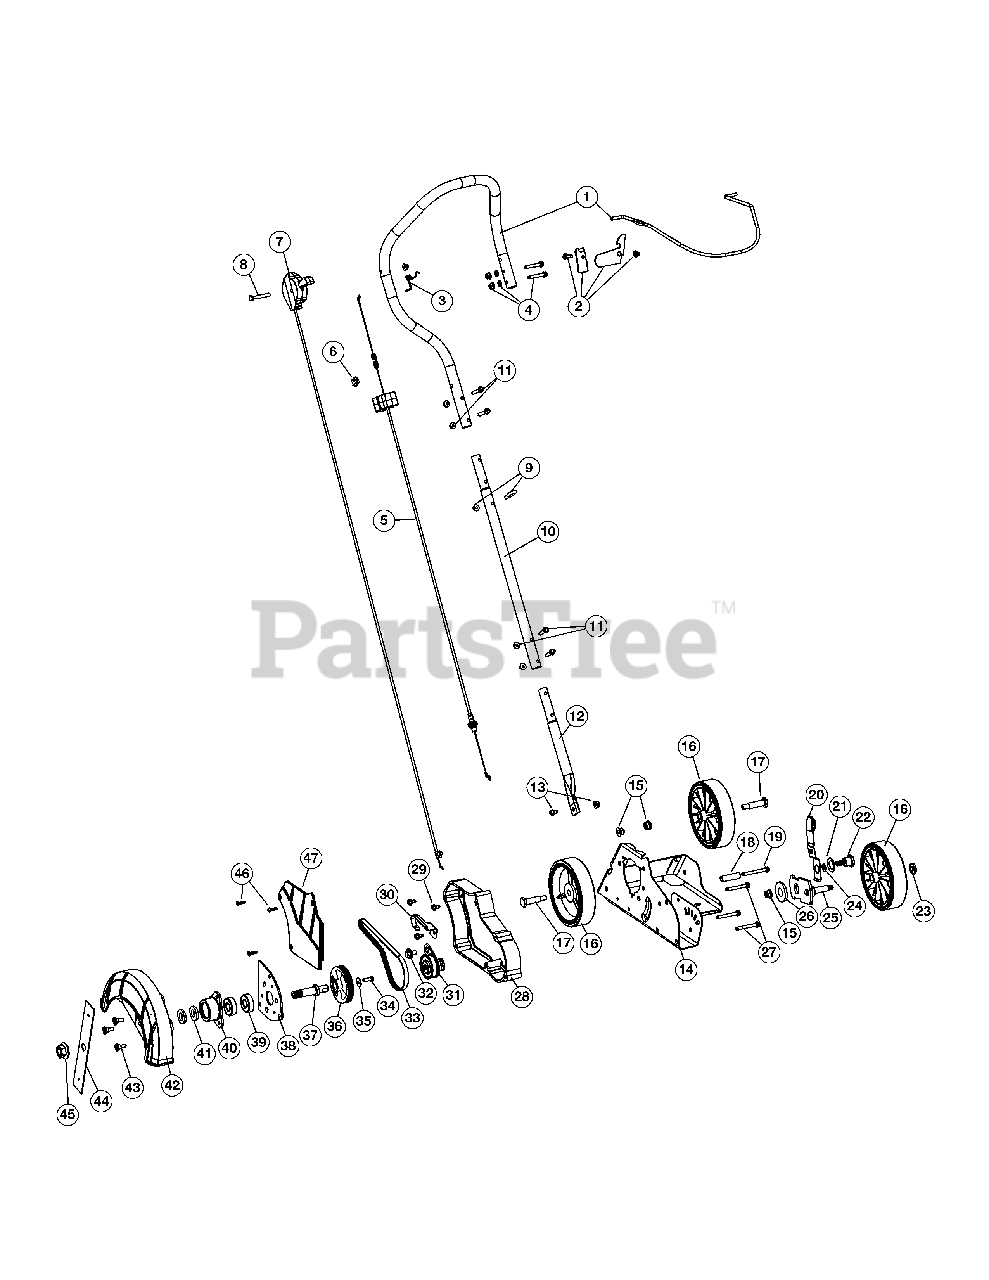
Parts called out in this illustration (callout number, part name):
1	Handle Assembly
2	Lockout Lever Assembly
3	Bale Spring
4	Lockout Hardware Assembly
5	Tensioner Cable Assembly
7	Throttle Assembly
8	Throttle Hardware Assembly
9	Starter Rope Guide Assembly
10	Middle Handle Assembly
11	Handle Hardware Assembly
12	Lower Handle
13	Lower Handle Screw & Nut Assembly
14	Edger Frame
15	Lock Nut
16	Wheel
17	Wheel Bolt
18	Spacer
19	Spacer Screw
20	Height Adjustment Lever Assembly
21	Washer
22	Shoulder Screw
23	Nut
24	Washer
25	Pivot Arm
26	Height Adjustment Spacer
27	Spindle Plate Screw
28	Spindle Spacer
29	Screw
30	Belt Retainer
31	Idler Pulley Assembly
32	Shoulder Screw
33	Belt
34	Screw
35	Washer
36	Pulley
37	Blade Spindle
38	Spindle Plate
39	Bearing
40	Bearing Cup
41	Washer
42	Blade Guard
43	Screw
44	Edger Blade
45	Nut
46	Screw
47	Belt Cover
